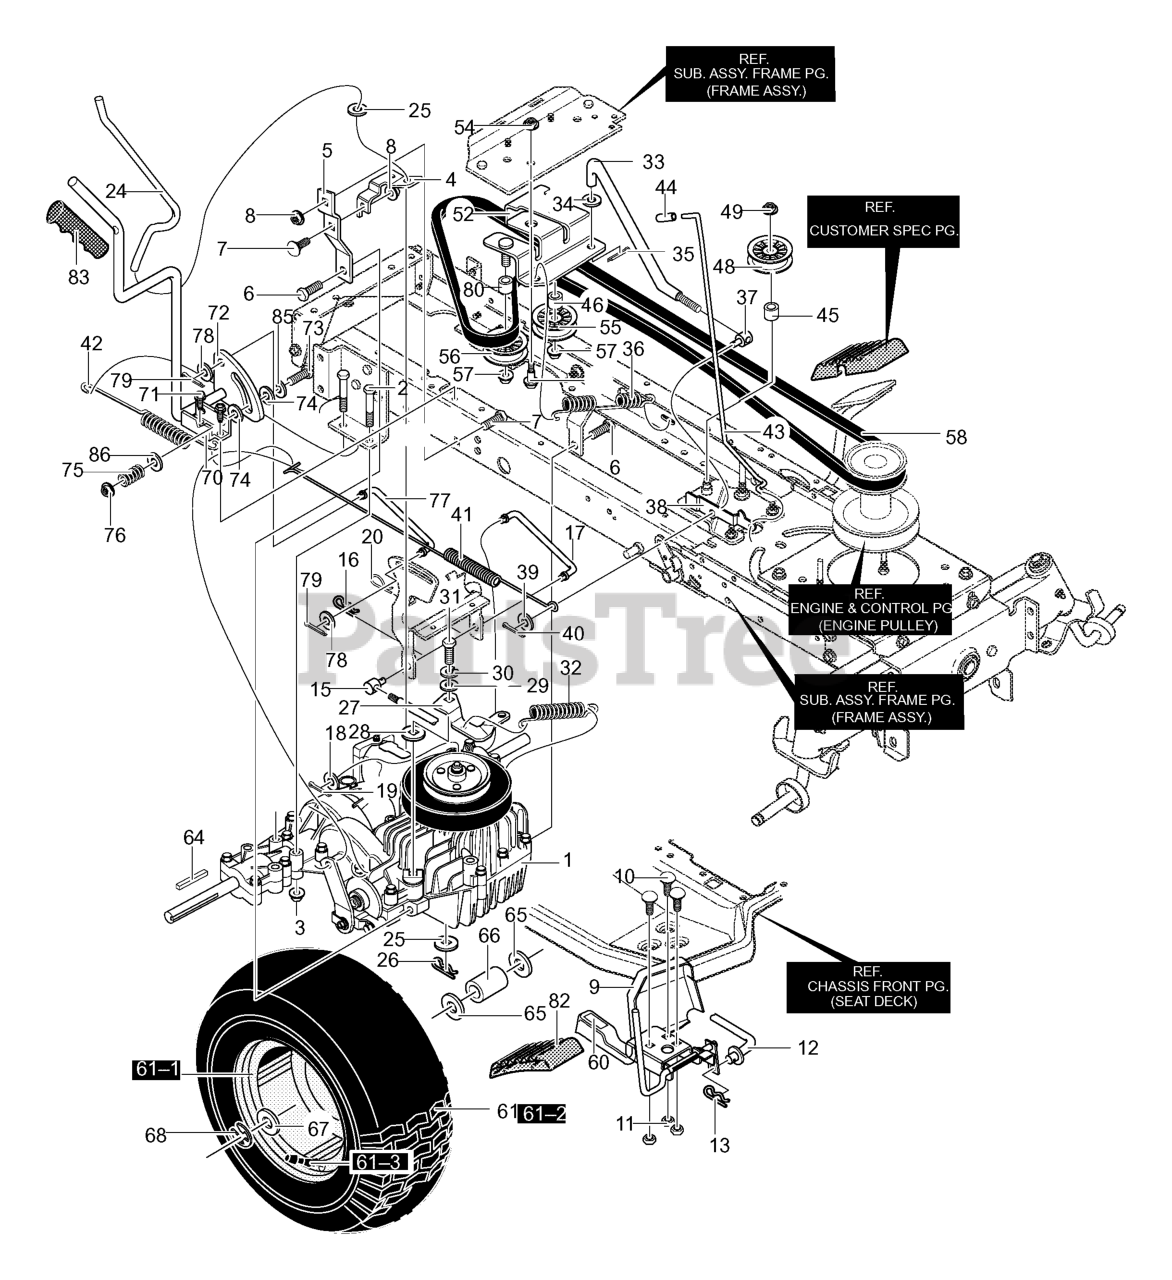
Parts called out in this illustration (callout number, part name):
1	Transaxle, VST205 **
2	Screw, 5/16-18 x 2.50
3	Nut, 5/16-18 Wdfllk
4	Bracket, Disconnect
5	Torque Strap
6	Screw, 5/16-18 x 0.75
7	Bolt, 5/16-18x.63
8	Nut, 5/16-18 Wdfllk
9	Pedal Assy., Hydro
10	Bolt, 5/16-18x.75
11	Nut, 5/16-18
12	Rod, Pedal Link
13	Hair Pin
15	Adjust Nut 1/2-13
16	Hair Pin
17	Rod Hydro Link
18	Flat washer
19	Cotter Pin
20	Hair Pin
24	Rod, Disconnect
25	Washer, Flat
26	Pin, Cotter
27	Arm Disconnect
29	Flat washer
30	Washer
31	Screw, 1/4-28x.75
32	Spring, Extension
33	Rod, Clutch
34	Flat washer
35	Cotter Pin
36	Spring, Clutch
37	Nut, Adjusting
38	Latch, Park Brake
39	Flat washer
40	Cotter Pin
41	Spring, Extension
42	Spring, Tension
43	Park Brake Rod
45	Spacer 1/2 to 17MM
46	Spacer 1/2 to 17MM
48	Pulley, Idler
49	Nut, 3/8-16
52	Asm., Bracket Idler
53	Bolt, 3/8-16
54	Nut, 3/8-16
55	Pulley, Idler
56	Pulley, Idler
57	Nut, 3/8-16
58	Belt, Motion Drive
60	Pad, Toe Sandpaper
61	Tire & Rim
61-1	Valve Stem
64	Key, Square
65	Flat washer
66	Spacer .87x1.78
67	Flat washer
68	Ring, E
70	Bracket, Mount Hand Ctrl
71	Screw, 5/16-18 x 0.75
72	Assy., Lever Hand Ctrl
73	Bolt, HHSH 5/16-18
74	Washer, Friction
75	Spring, Compression
76	Nut, 5/16-18
77	Link, Cruise Control
78	Flat washer
79	Cotter Pin
80	Spacer, 1/2 to 17MM
82	Pad, Speed Ctrl Pedal
85	Flat washer
86	Flat washer
